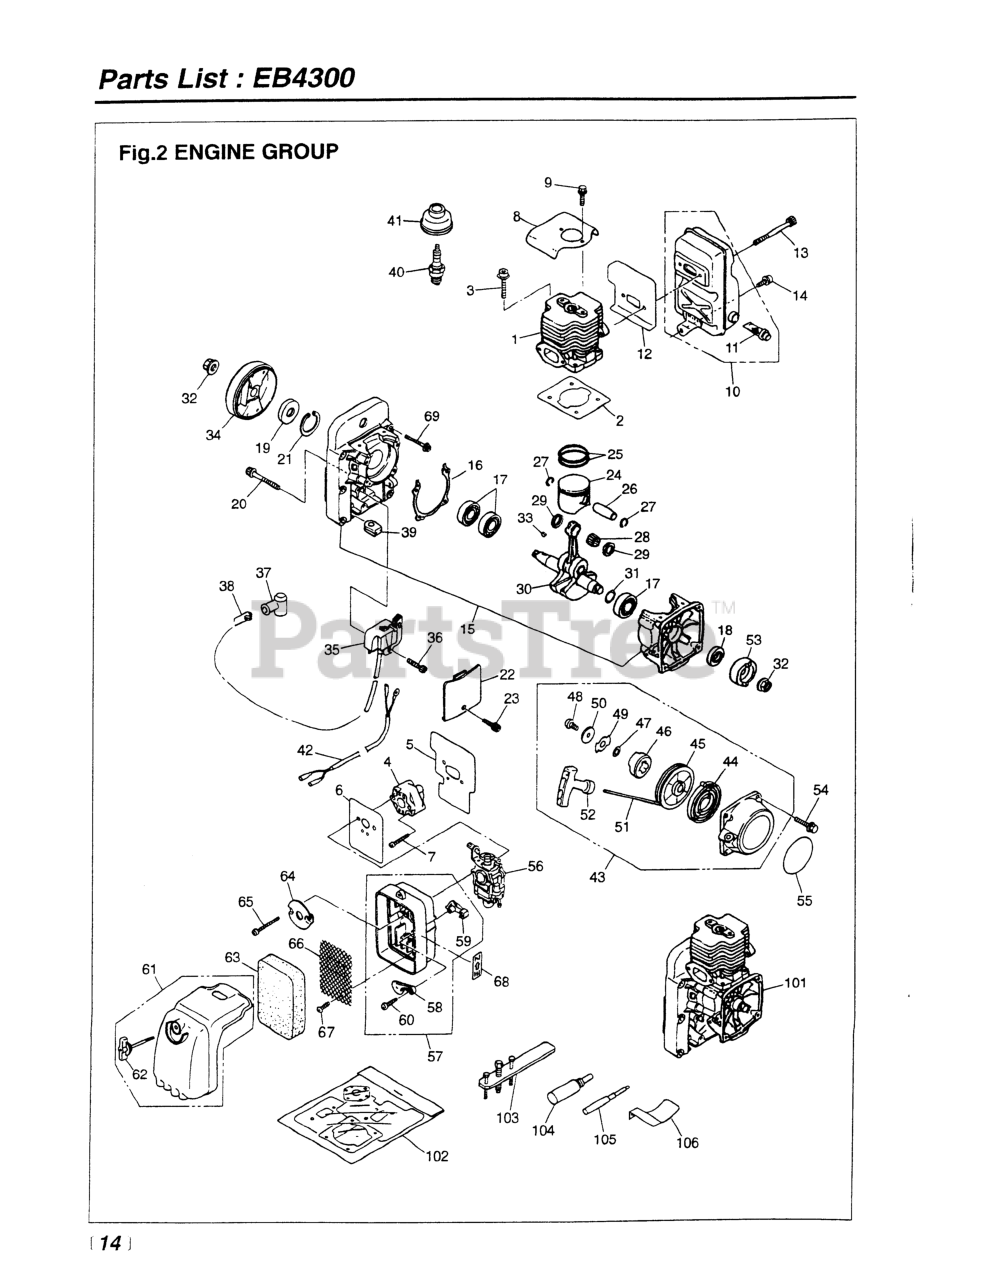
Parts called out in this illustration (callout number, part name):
1	CYLINDER (RPLS -12111)
2	GASKET, BASE
3	BOLT, M5 x 22
5	GASKET
6	GASKET
7	SCREW, M5 x 35
9	BOLT, M5 x 10
11	ARRESTER
12	GASKET
13	BOLT, M6 X 70
14	BOLT, M6 X 12
15	CRANKCASE COMPL
16	GASKET
18	SEAL, OIL - STARTER SIDE
20	BOLT, M5 X 30
21	RING, SNAP, M35 X 1.5
22	COVER
23	BOLT, M4 X 16
24	PISTON (RPLS -41110)
25	RING, PISTON (RPLS -41210)
26	PIN, PISTON (RPLS. 1490-41316)
27	RING, SNAP
28	BEARING
29	WASHER (RPLS 1491-41510)
30	CRANKSHAFT COMPLETE
31	SHIM (REPLACES 848-870-G000)
32	NUT, M10
33	KEY
34	ROTOR (USE 2750-71111)
35	COIL ASSEMBLY, IGINITION
36	BOLT, M4 X 16
38	SPRING
39	GROMMET
41	CAP
42	CORD COMPLETE
44	SPRING (RPLS -75220)
46	DOG
47	WASHER
48	SCREW
49	RETAINER (RPLS 1861-75161)
50	WASHER
51	ROPE
52	KNOB
53	PULLEY (RPLS -75210)
54	BOLT, M5 x 20
56	CARBURETOR ASSEMBLY
57	BODY, CLEANER
58	PLATE
59	LEVER
60	SCREW (REPLACES 50030272)
62	KNOB
63	ELEMENT (RPLS -82310)
64	PLATE (REPLACES -82511)
65	SCREW, M5 x 60
66	SCREEN (RPLS -82351)
67	SCREW
68	LABEL
69	BOLT, M6 X 40
101	BLOCK, SHORT
102	KIT, GASKET
103	PULLER ASSY
104	STOPPER (TOOL) (RPLS 3320-9641
105	GUIDE (TOOL)
